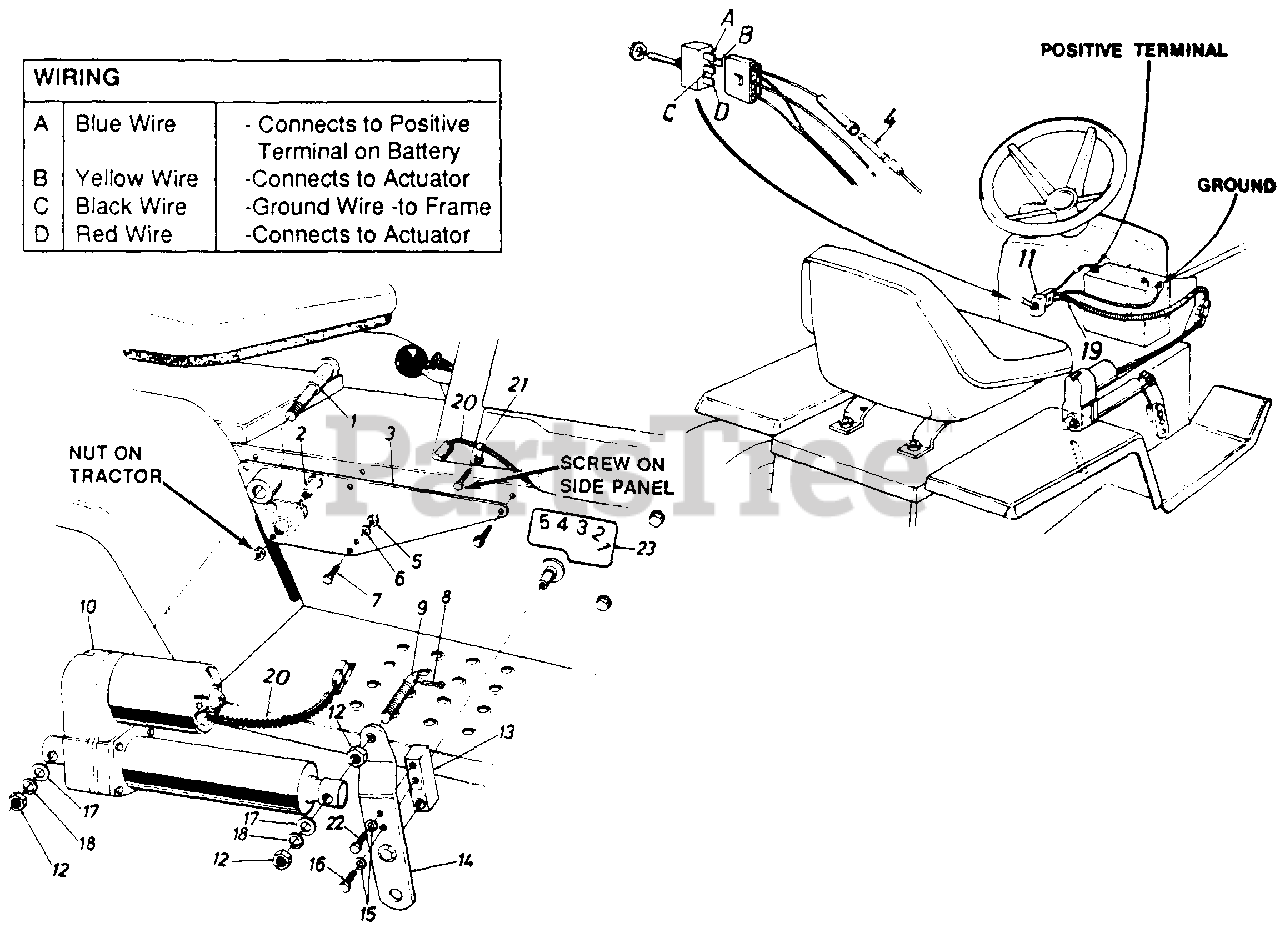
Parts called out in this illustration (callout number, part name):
1	Pivot Pin
2	Shld. Bolt .626 Dia. x .96"
5	Hex Nut 1/4"-28 Thd.
6	L-Wash. 1/4" I.D.
7	Hex Bolt 1/4-28 x .75" Lg. (Gr. 5)
8	Cotter Pin
9	Indicator & kg. Pin
10	Electric Actuator
11	Toggle Switch
12	Hex Jam Nut 1/2-13 Thd.
13	Lift Shaft Drive
16	Hex Bolt 5/16-24 x 1.0" Lg.(Gr. 5)
17	Fl-Wash..53" I.D. x .93" O.D.
18	L-Wash. 1/2" I.D.
19	Wire Harness
20	Plastic Harness
21	Clamp
22	Hex Bolt 5/16-18 x 1" Lg. (Gr.5)
23	Label
A	Connects to Positive Terminal on Battery
B	Connects to Actuator
C	Ground Wire to Frame
D	Connects to Actuator
